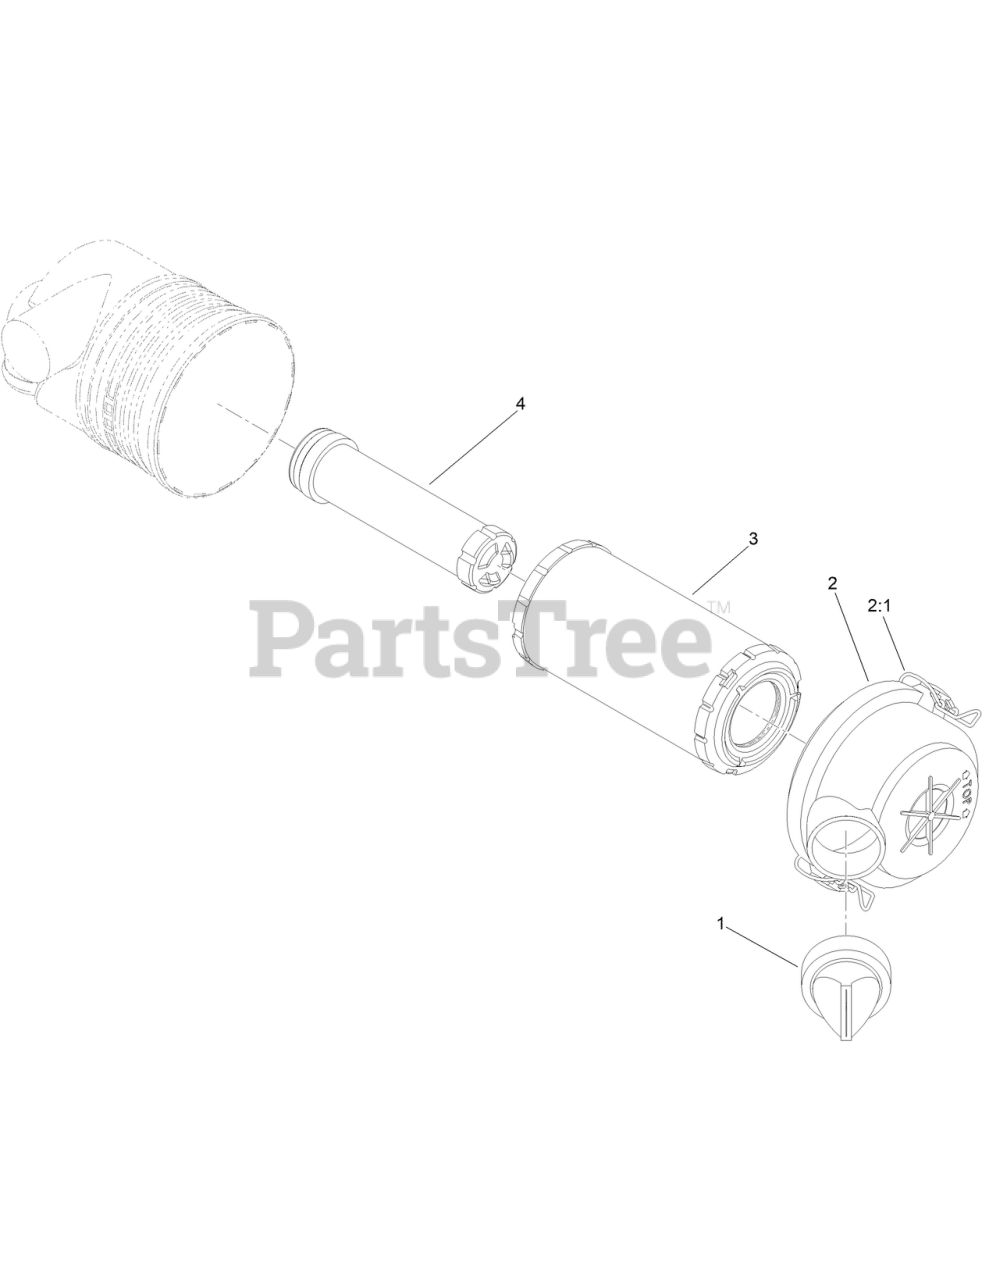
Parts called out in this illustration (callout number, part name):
1	VALVE-VACUATOR
2	COVER ASM
2:1	LATCH-CLEANER, AIR
3	FILTER-AIR
4	FILTER-ELEMENT, SAFETY
